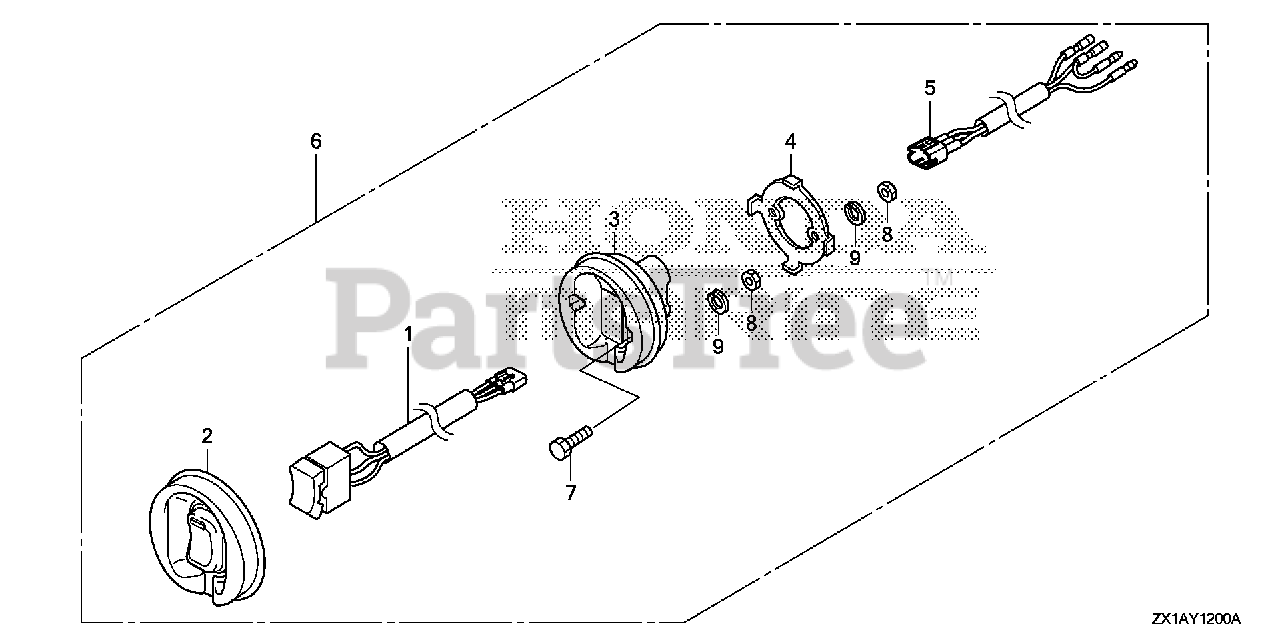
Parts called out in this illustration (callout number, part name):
1	SWITCH ASSY., TROLLING CONTROL (ENGINE NO.)
2	RUBBER, TROLLING CONTROL SWITCH PANEL (ENGINE NO.)
3	BODY, TROLLING CONTROL SWITCH PANEL (ENGINE NO.)
4	BRACKET, TROLLING CONTROL SWITCH PANEL (ENGINE NO.)
5	HARNESS, TROLLING CONTROL SWITCH PANEL (ENGINE NO.)
6	PANEL ASSY., TROLLING CONTROL (ENGINE NO.)
7	BOLT, HEX. (4X20) (ENGINE NO.)
8	NUT, HEX. (4MM) (ENGINE NO.) (NOT AVAILABLE)
9	WASHER, SPRING (4MM) (ENGINE NO.)
